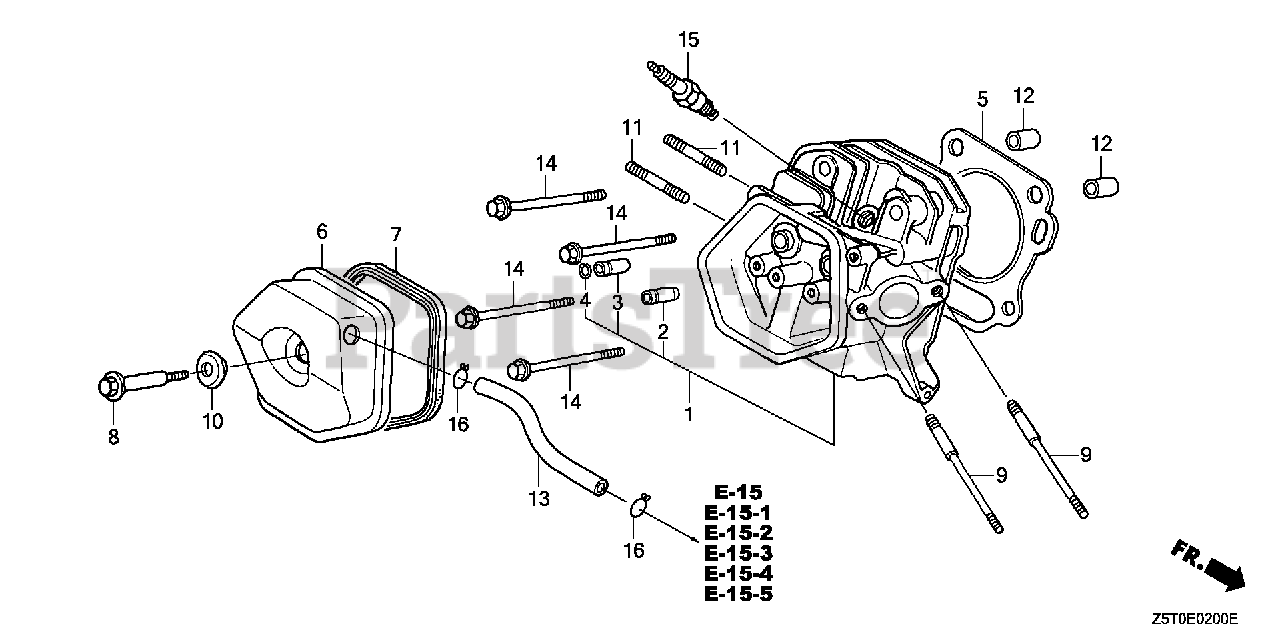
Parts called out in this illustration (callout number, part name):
1	CYLINDER HEAD
2	GUIDE, VALVE (OS)
3	GUIDE, EX. VALVE (OS)
4	CLIP, VALVE GUIDE
5	GASKET, CYLINDER HEAD (THAI LEAKLESS)
6	COVER, HEAD
7	GASKET, CYLINDER HEAD COVER
8	BOLT, HEAD COVER
9	BOLT, STUD (8X131.5)
10	WASHER, HEAD COVER
11	BOLT 2, STUD (8X32)
12	PIN A, DOWEL (12X20)
13	BULK HOSE, VACUUM (11X1000) (Honda Code 4537312). (11X105)
14	BOLT, FLANGE (10X80)
15	SPARK PLUG (BPR5ES) (NGK)
15	SPARK PLUG (W16EPR-U) (DENSO)
15	SPARK PLUG (BPR6ES) (NGK)
